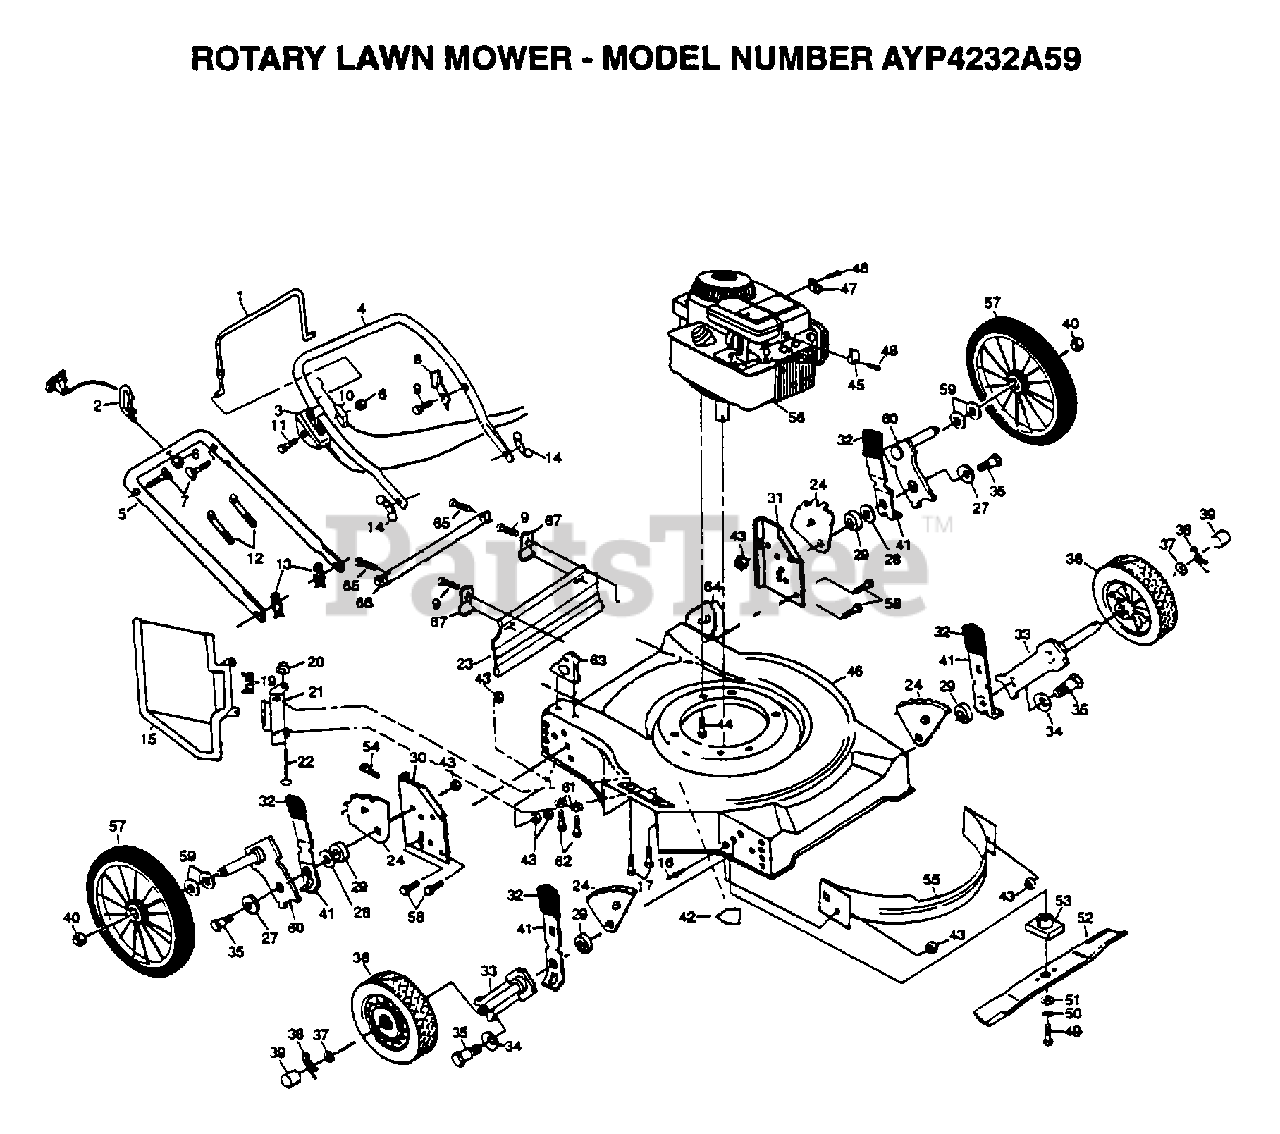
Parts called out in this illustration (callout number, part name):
1	CONTROL BAR PM
2	ROPER GUIDE PM
3	CONTROL THROTTLE
7	BOLT.HANDLE.LM
8	"BRKT,UPSTOP"
9	TAPPING SCREW
10	"CABLE,ENG ZONE CO"
11	SCREW.HXHD.WASH.
13	HAIRPIN COTTER
14	"NUT,WING PM"
16	BLIND RIVET
17	SCREW
19	"SPRING,TORSION"
20	PUSH ON SPEED NUT
21	"BRKT,HSG"
22	"ROD,HINGE "
23	SKIRT.REAR.22SD.
24	BRKT.WHL.ADJ
28	WASHER PM
30	BRACKET.SUPT.WHEL
31	BRACKET.SUPT.WHEL
32	KNOB PM
33	AXLE ARM
34	"WASHER, BELLEVIL."
35	BOLT SHLD 3/8-16
36	WHEEL.ASM
37	WASHER
38	RETAINER CLIP PM
39	HUB CAP-PLASTIC
40	HEX FLANGE LOCKNT
41	SPRING SELECTOR
42	DECAL-DANGER PM
43	LOCKNUT PM
44	SCREW
45	CABLE CLAMP
46	HOUSING KIT
47	GUIDE CLIP PM
48	SCREW PM
49	SCREW
50	LOCKWASHER
51	"WASHER,HARDEN"
52	"BLADE.MULCH.22"""
53	BLADE ADAPTOR
54	SCREW
55	BAFFLE.FRT/REAR
57	WHEEL & TIRE PM
59	WAVE WASHER
60	AXLE ARM ASSY R
61	STEEL WASHER
62	SCREW
65	SCREW
66	ROD.SUPPORT.WB.
67	"BRKT,DEFL PM"
